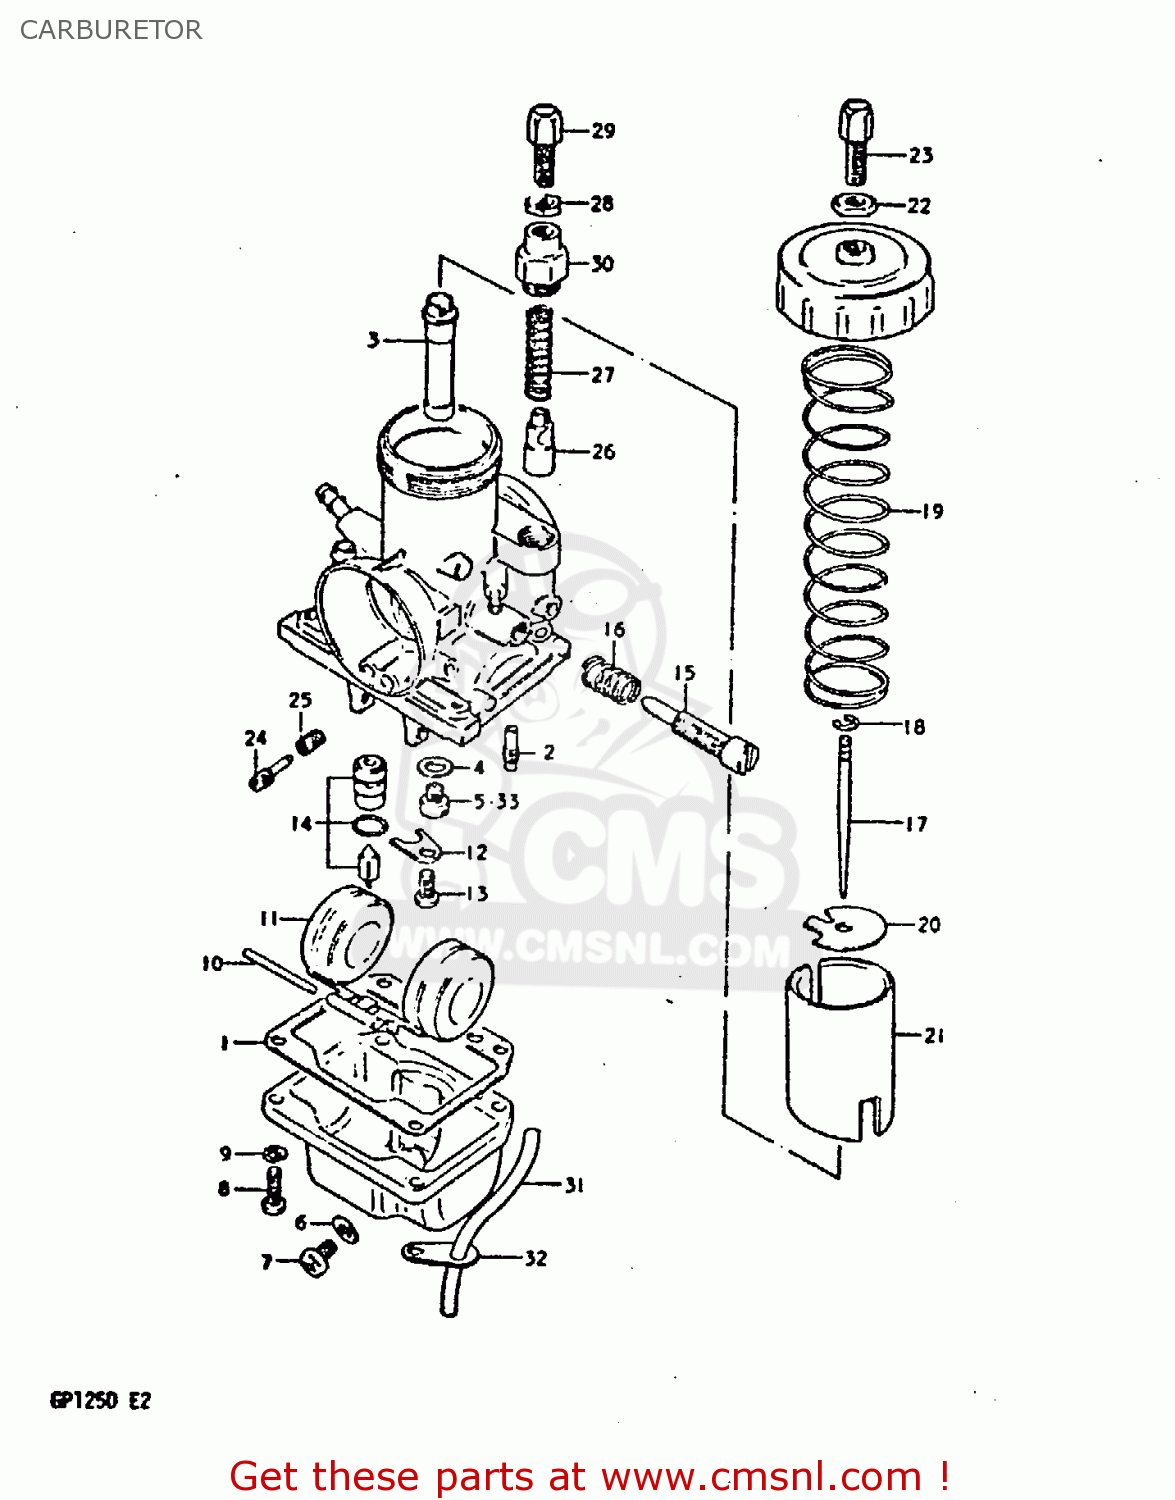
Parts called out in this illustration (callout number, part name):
1	GASKET,FLOAT CAHMBER (NAS)
2	JET,PILOT(25)
3	JET,NEEDLE
4	WASHER
5	JET,MAIN(90)
6	GASKET,DRAIN,PLUG (NAS)
7	PLUG
8	SCREW
9	LOCK WASHER
10	PIN,FLOAT
11	FLOAT
12	PLATE
13	SCREW
14	VALVE ASSEMBLY,NEEDLE
15	ADJUSTER
16	SPRING,THROTTLE SCREW
17	NEEDLE, JET (4EJ14)
18	CLIP
19	SPRING,THROTTLE VALVE
20	PLATE
21	VALVE,THROTTLE
22	NUT
23	ADJUSTER,CABLE
24	SCREW,PILOT AIR
25	SPRING
26	PLUNGER,STARTER
27	SPRING
28	NUT
29	ADJUSTER,CABLE
30	CAP
31	HOSE
32	PLATE
33	JET
